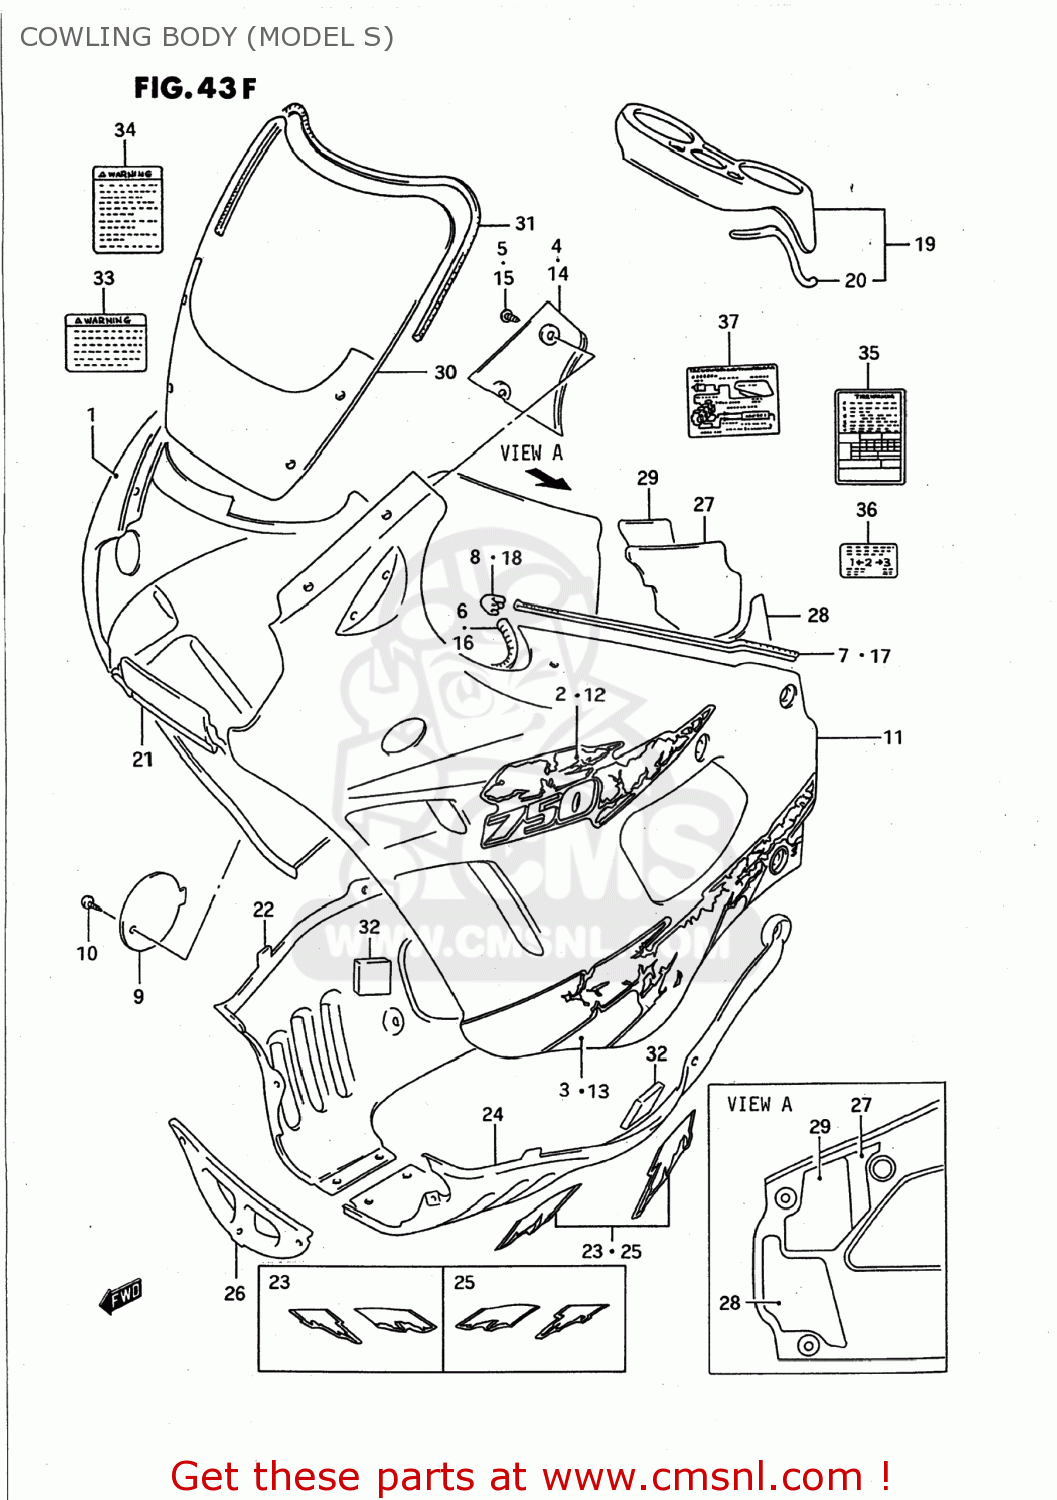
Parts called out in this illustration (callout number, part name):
1	COVER ASSEMBLY,COWLING,RIGHT
2	TAPE,BODY COWL SIDE UPR,R
3	TAPE,BODY COWL SIDE,R
4	COVER,COWLING METER SIDE,R
5	SCREW
6	MOLD,COWLING
7	MOLDING
8	JOINT,MOLDING END
9	LID,OIL
10	SCREW(6X16)
11	COVER ASSEMBLY,COWLING,LEFT
12	TAPE,BODY COWL SIDE UPR,L
13	TAPE,BODY COWLING SIDE,LEFT
14	COVER,COWLING METER SIDE,L
15	SCREW
16	MOLD,COWLING
17	MOLDING
18	JOINT,MOLDING END
19	COVER,METER
20	MOLDING,METER COVER
21	PANEL,COWLING CTR
22	COVER,COWLING UNDER,R
23	TAPE SET,COWL UNDER,R
24	COVER,COWLING UNDER,L
25	TAPE SET,COWLING,UNDER
26	COVER,COWLING UNDER FR
27	BALANCER SHEET,COWLING,R
28	SHEET,COWLING BALANCER
29	CUSHION,COWLING,R
30	WINDSCREEN
31	MOLDING,WINDSCREEN
32	CUSHION,UNDER COWLING
33	LABEL
34	LABEL (WARNING SCREEN)
35	LABEL (TIRE AIR PRESSURE)
36	LABEL (REAR SHOCK ABSORBER)
37	LABEL (VACUUM HOSE ROUTING)
